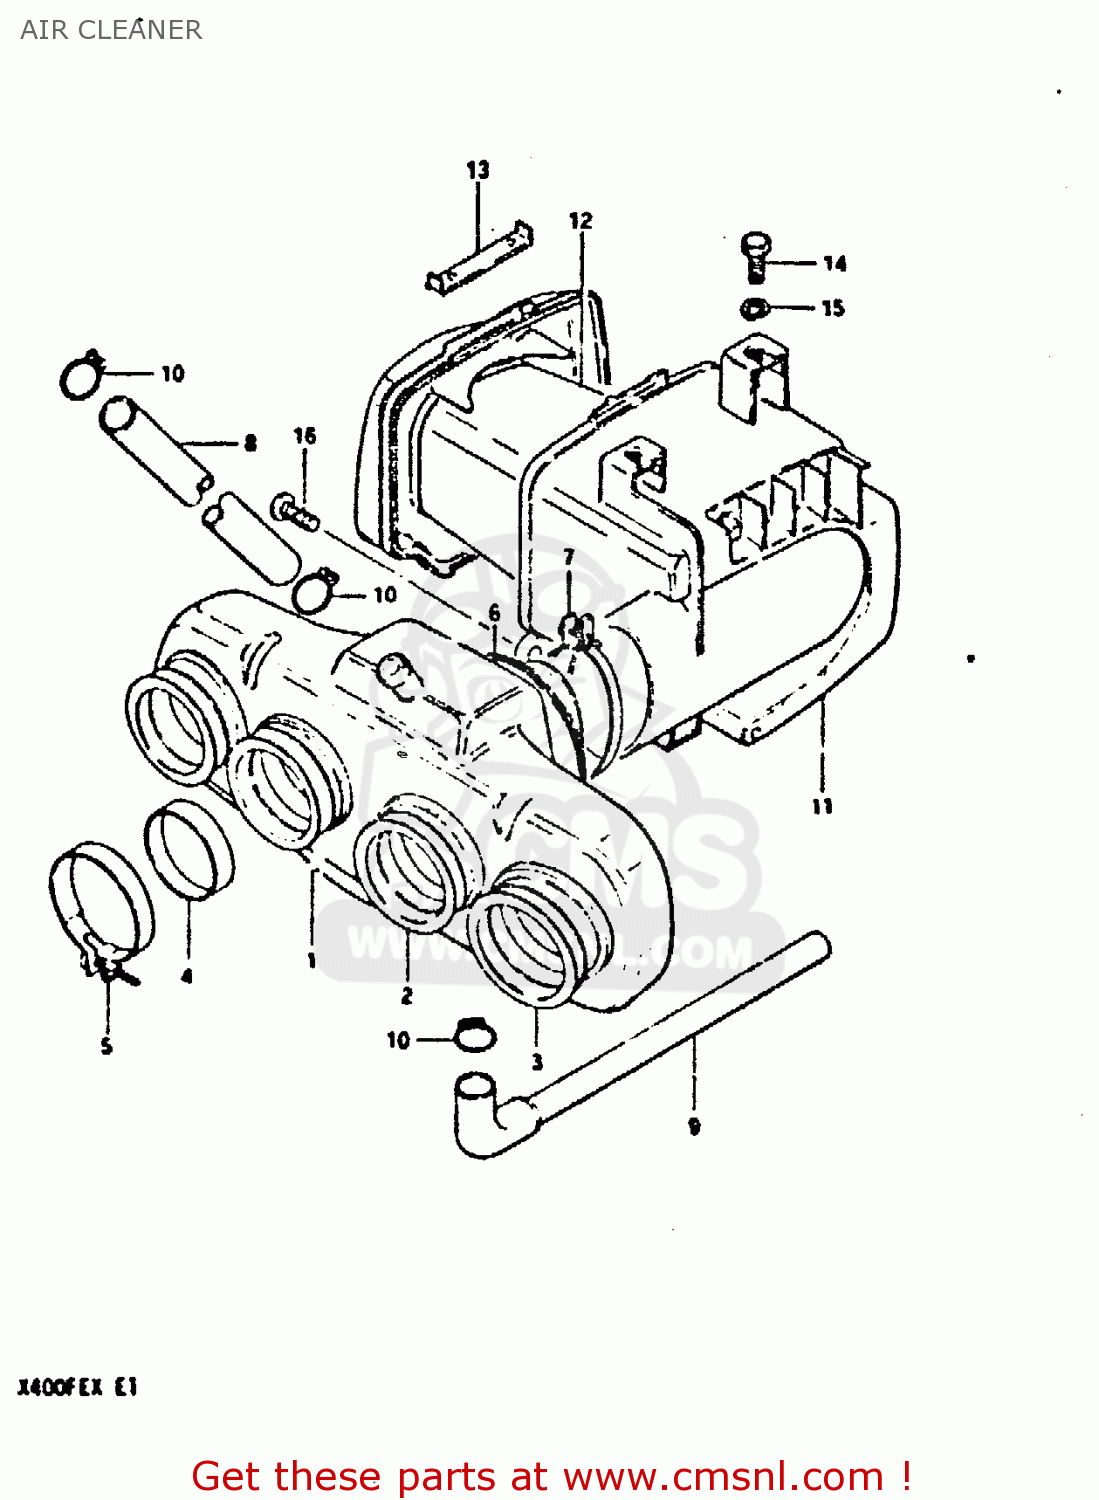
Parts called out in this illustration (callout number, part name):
1	CASE ASSY, FRONT
2	TUBE,INNER
3	TUBE,OUTER
4	RING,CARBURETOR AIR IN
5	CLAMP
6	JOINT,HOSE AIR CLEANER
7	CLAMP
8	TUBE,BREATHER
9	DRAIN TUBE
10	CLIP
11	CASE SET, REAR
12	FILTER ASSY
13	SLIDER
14	BOLT, UPPER
15	LOCK WASHER
16	SCREW
